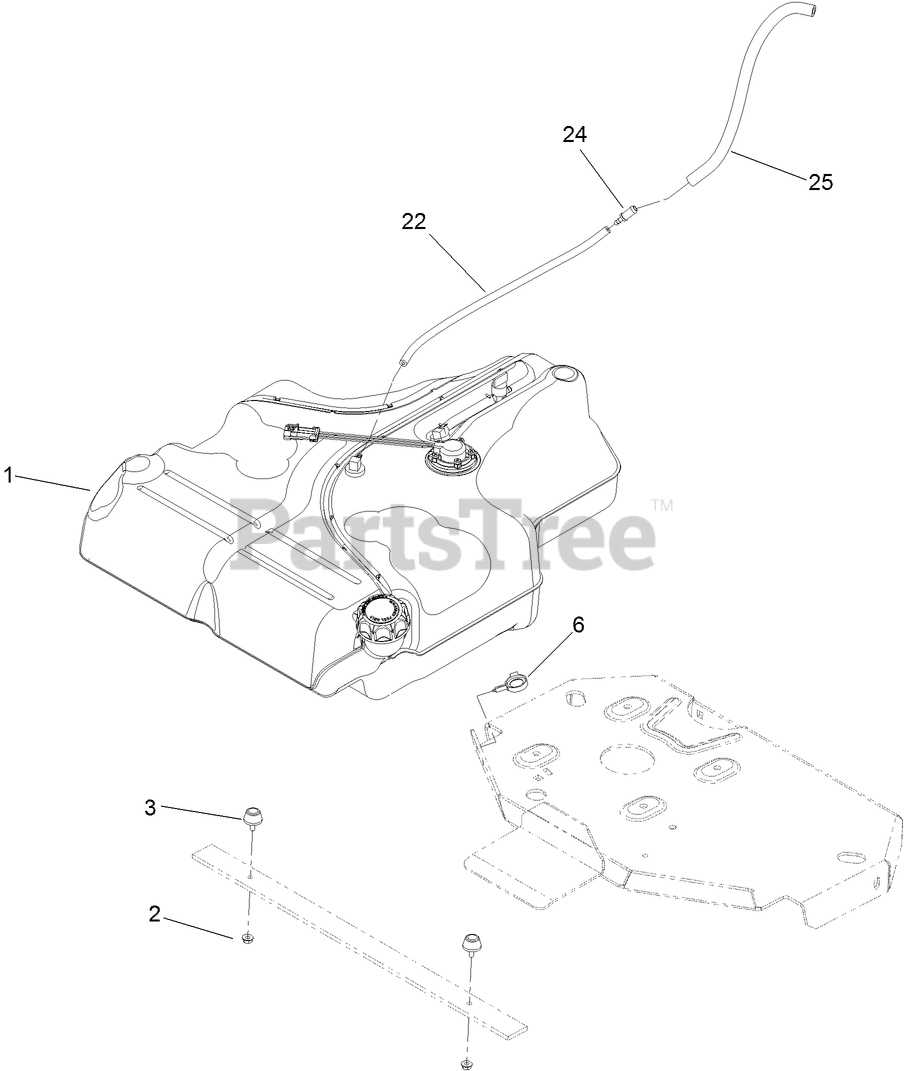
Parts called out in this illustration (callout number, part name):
1	FUEL TANK ASM
2	NUT-HF
3	BUMPER-RUBBER
6	CLAMP-HOSE
22	HOSE-FUEL
24	FITTING-STRAIGHT
25	HOSE-FUEL
